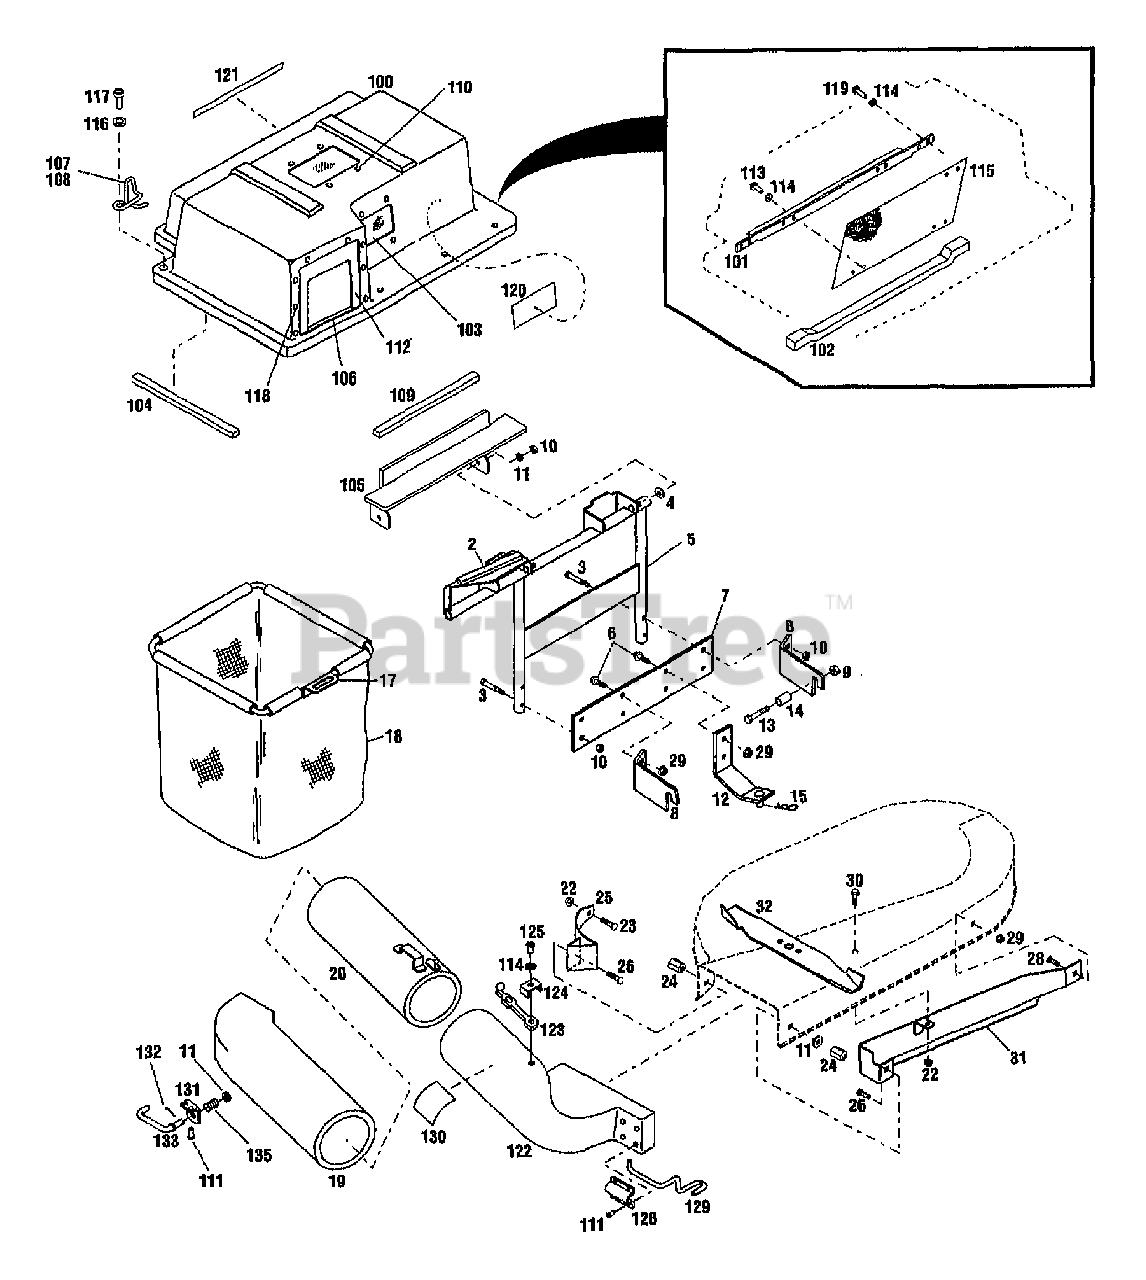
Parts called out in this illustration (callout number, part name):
2	SEAL-COVER 9.5"
3	SCR-HH 5/16-18X2.00
4	WASHER-.87X.34X.06 NYLON
5	ASSM-BAG SUPPORT
6	SCR-HFLK 5/16-18X1.00 ZP
7	PLATE-SUPPORT
8	PLATE-SIDE MOUNTING
9	NUT-TOP LOCK 1/2-13 ZP
10	NUT-TOP/LK 5/16-18 ZP
11	WASHER-FLAT 5/16 SAE
12	SUPPORT-MOUNTING
13	SCR-HH 1/2-13X1.5 G5 ZP
14	SPACER-ATTACHMENT
15	PIN-HITCH .125X2.56 ZP
17	ASSM-FRAME GRASSBAG
18	ASSM-GRASS BAG
19	ELBOW
20	ASSM-GRASS GUIDE
22	NUT-HF/LK 1/4-20 ZP
23	SCR-CARR 1/4-20X.75 G2 ZP
24	NUT GUIDE 5/16-18 ZP
25	BAFFLE-REAR
26	SCR-CARR 5/16-18X.62 G2 ZP
28	SCR-CARR 5/16-18X.75 G2 ZP
29	NUT-HFLK 5/16-18 ZP
30	SCR-HH 1/4-20X.625
31	BAFFLE-FRONT
32	BLADE-MWR RH HILIFT
100	COVER-GRASSBAG
101	BRKT-ANGLE
102	COVER-SEAL
103	WINDOW
104	SEAL-COVER
105	ASSM-HINGE SUPPORT
106	CHUTE REINFORCEMENT
107	COVER-LOCK RH
108	COVER-LOCK LH
109	SEAL-COVER
110	RIVET-POP
111	RIVET-POP 3/16"DIA
112	GASKET-CHUTE
113	RIVET-POP 3/16 X 5/8
114	WASHER-.505X.22X.05
115	SCREEN
116	WASHER-.88X.2X.059
117	RIVET-POP 3/16X1/2
118	RIVET-POP .125
119	RIVET-POP
120	DECAL-INST
121	DECAL-LOGO
122	ASSM-DISCHARGE CHUTE
123	LATCH-RUBBER
125	POP-RIVET
128	LEVER-CLAMP
129	LEVER-LOCK
130	DECAL-WARNING
131	BRACKET-CHUTE
132	PIN-ROLL .093 DIAX.62
135	SPRING
